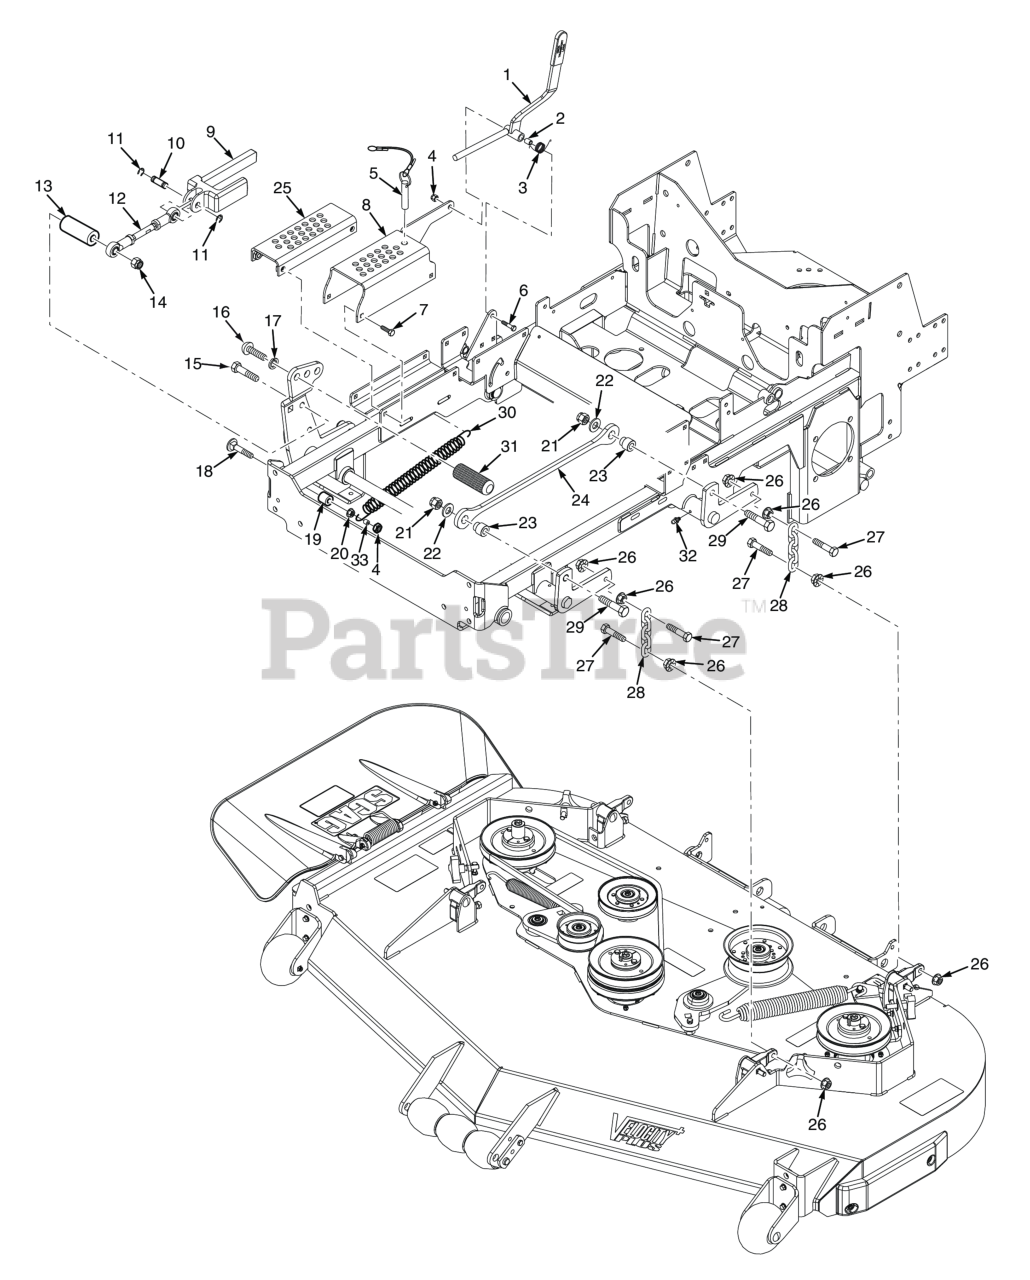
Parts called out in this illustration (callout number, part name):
1	Deck Latch Assembly (Includes Grip)
1	Grip, Deck Latch
2	Spacer, Deck Latch
3	Spring, Torsion - Lever Return
4	Bolt, Hex Head 3/8-16 x 1" Ser. Flg.
5	Lanyard, Deck Height Pin Assembly
6	Capscrew, Hex Head 3/8-16 x 2-1/2"
7	Bolt, Hex Wshr Head 5/16-18 x 1-1/4"
8	Adjustment Bracket, Cutting Height
9	Slide, Height Adjust (INCL. 10,11,12)
10	Pin, Deck Lift
11	Retaining Ring, 1/2" Ext. "E"
12	Linkage Assembly, Deck Lift
13	Spacer, Deck Lift Pedal
14	HEX LOCKNUT, ELASTIC STOP, 1/2-13
15	Bolt, Hex Head 1/2-13 x 4" (lower)
16	Capscrew, 5/8-11 x 1-1/2"
17	Lockwasher, 5/8" Spring
18	Carriage Bolt, 3/8-16 x 2-1/2"
19	Yoke, Front Caster Wheel
20	NUT, 3/8-16 SERRATED FLANGE HEX HEAD
21	HEX LOCKNUT, ELASTIC STOP, 1/2-13
22	Flat Washer, 1/2 (.562 x 1.375 x .109)
23	Pivot, Deck Link
24	Link, Decklift
25	Adjustment Bracket, Lower Cut Height
26	NUT, 3/8-16 SERRATED FLANGE HEX HEAD
27	Bolt, Hex Head, 3/8-16 x 1-1/2"
28	Chain, Deck Lift
29	Bolt, Hex Head 1/2-13 x 2-1/4"
30	Spring, Decklift
31	Foot Pedal, Height Adjustment
32	GREASE FITTING, STR. 1/4-28 SELF TAP.
33	Spacer, Deck Assist
